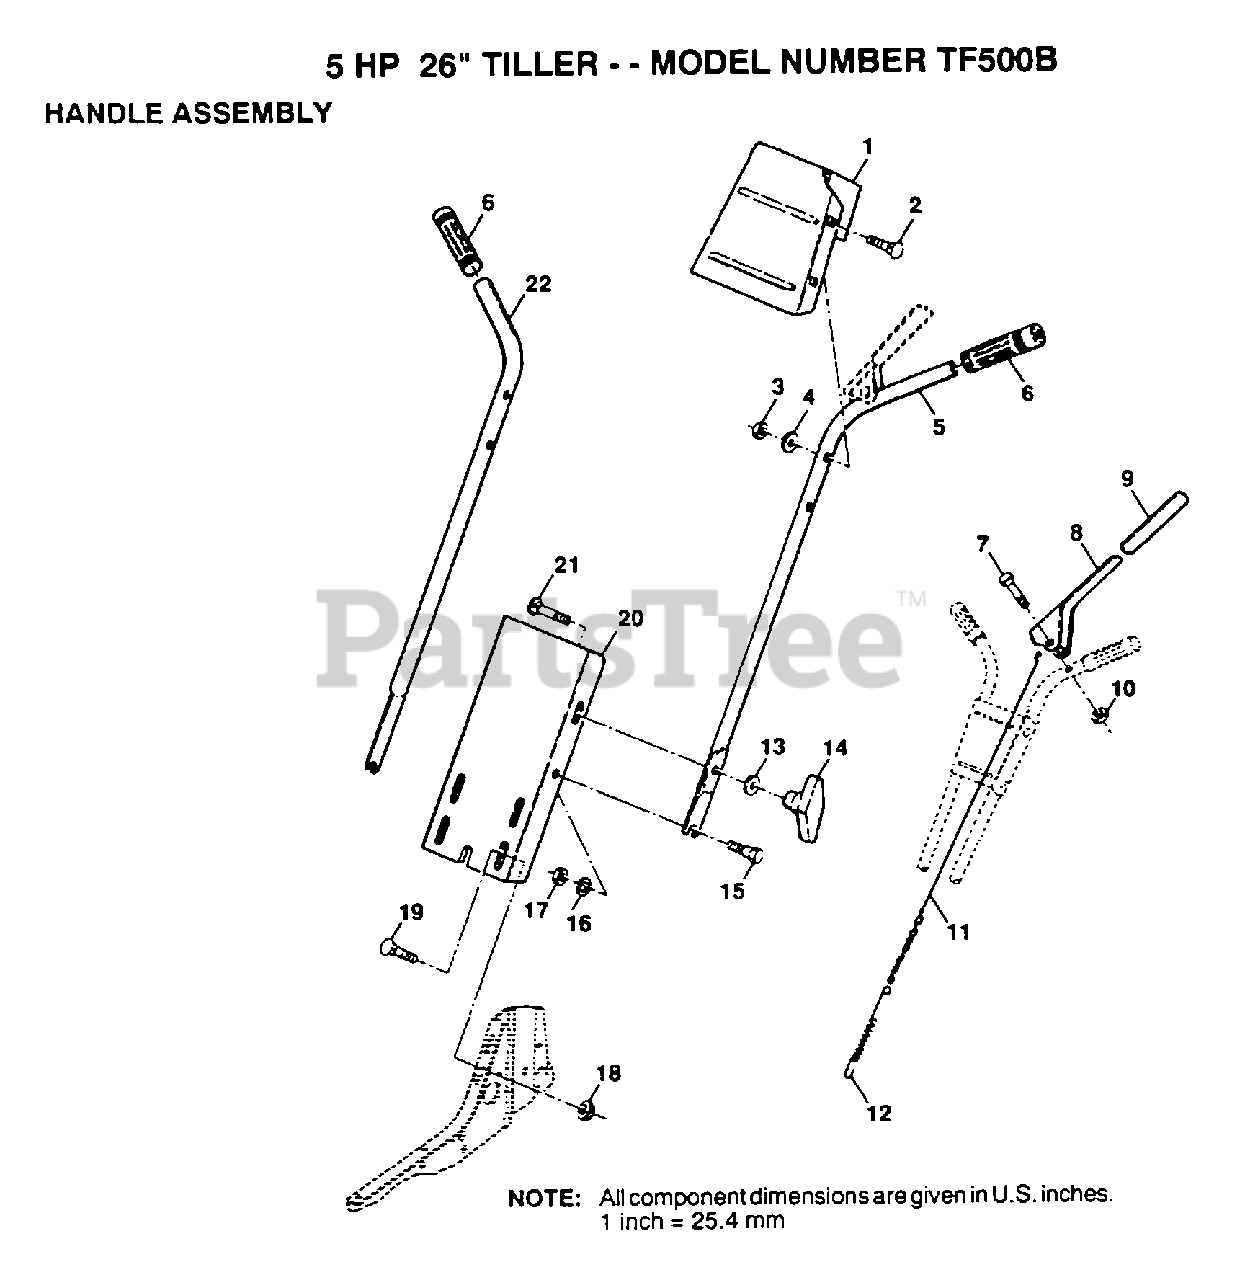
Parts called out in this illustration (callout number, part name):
1	HANDLE BRACKET
2	BOLT
4	WASHER
7	BOLT.HEX.5/16-1.5
9	GRIP T
12	SPRING EXT TI
13	WASHER
16	LOCKWASHER
17	NUT.HEX.5/16-18
18	NUT
19	BOLT
20	"PANEL,HANDLE"
21	BOLT
